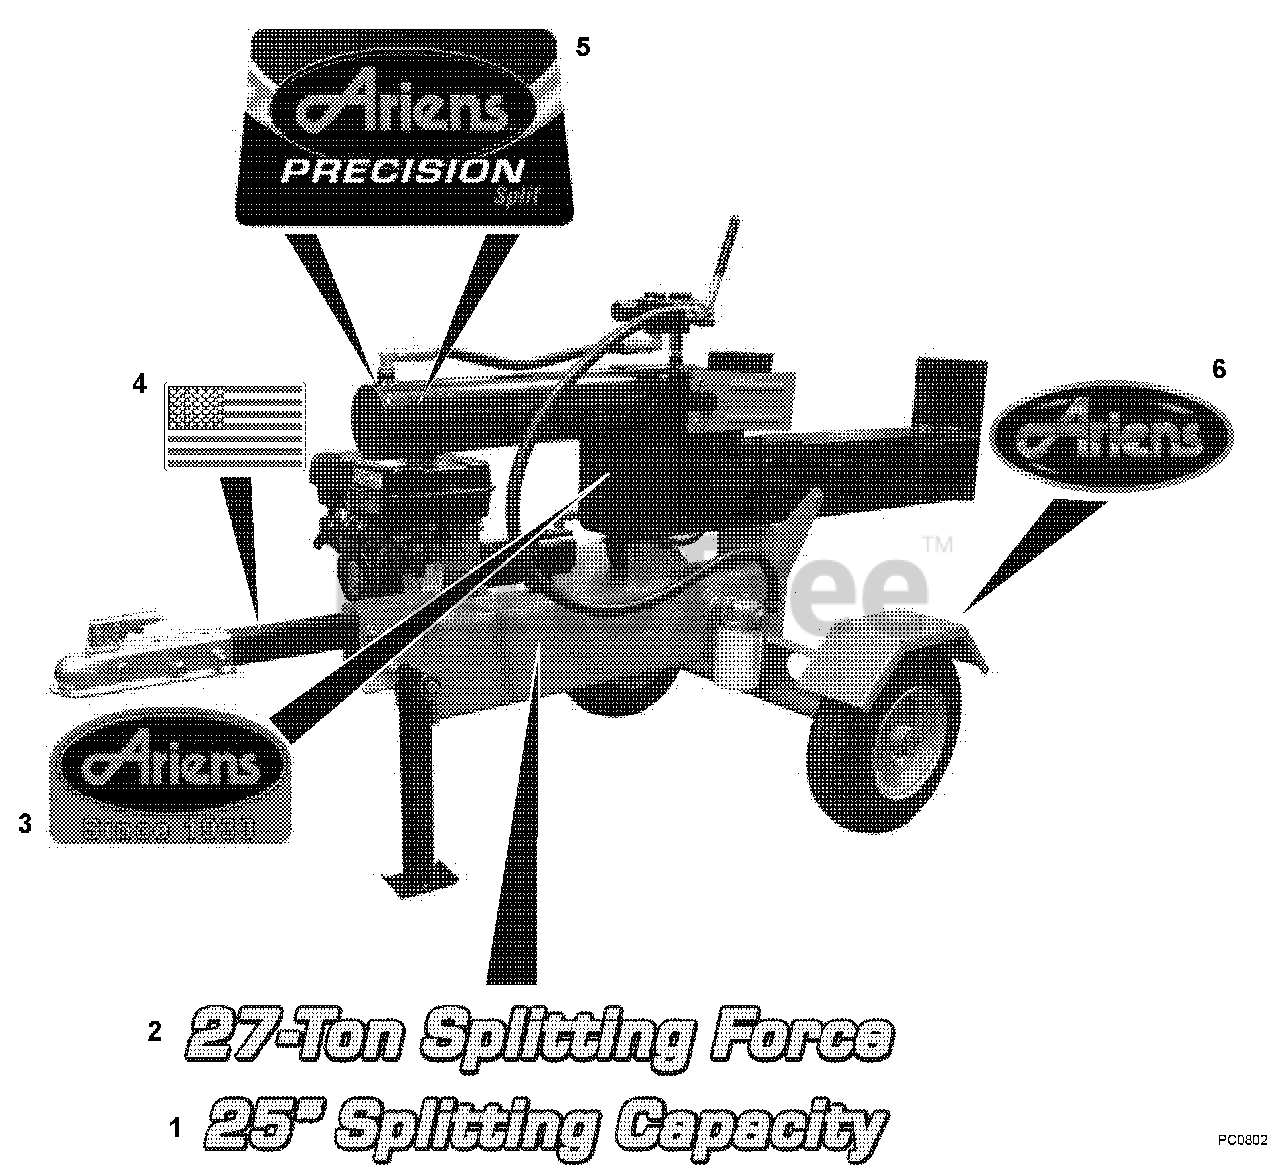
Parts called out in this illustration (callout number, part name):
1	DECAL, LOG SPLITTER-25" LENGTH
2	DECAL, LOG SPLITTER-27 TONS
3	DECAL, ARIENS SINCE 1933 LG
4	DECAL, AMERICAN FLAG
5	DECAL, LOG SPLITTER-PRECISION
6	DECAL, ARIENS JEWEL (LARGE)
